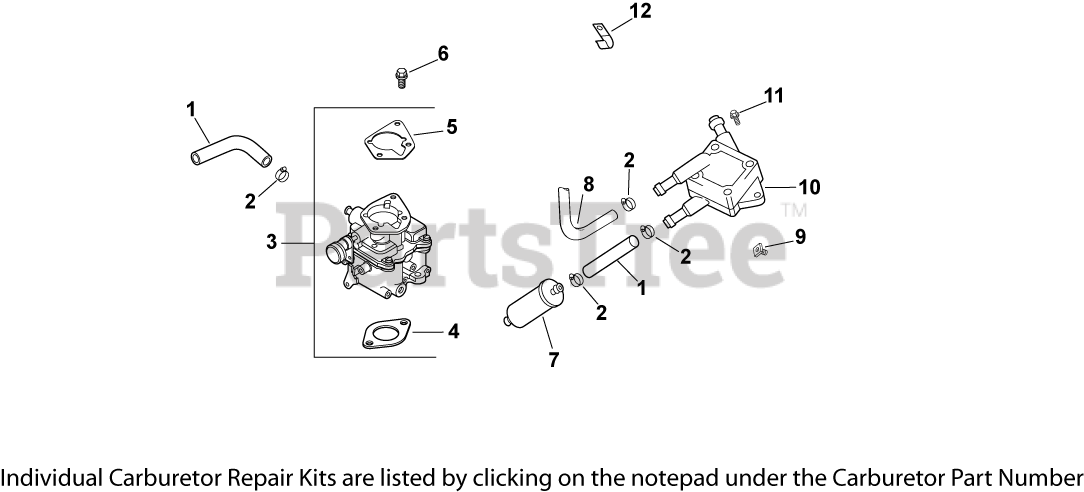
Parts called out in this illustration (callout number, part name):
1	HOSE,LW PERM.FUEL 24.00"-USE 25 111 81-S
2	CLAMP, HOSE (KM)-USE 25 237 31-S
3	KIT, CARBURETOR W/GASKETS
4	GASKET, CARBURETOR
5	GASKET, AIR CLEANER BASE
6	SCREW, FLG M6X1.0X12
7	FILTER, FUEL (9-12 MICRON)-USE 24 050 13
8	LINE, FLEXIBLE FUEL 15 1/2"
9	NUT, PLASTIC (KM)-USE 25 100 37-S
10	PUMP, FUEL
11	SCREW, TAP M6X1.7X18
12	CLIP, CABLE
